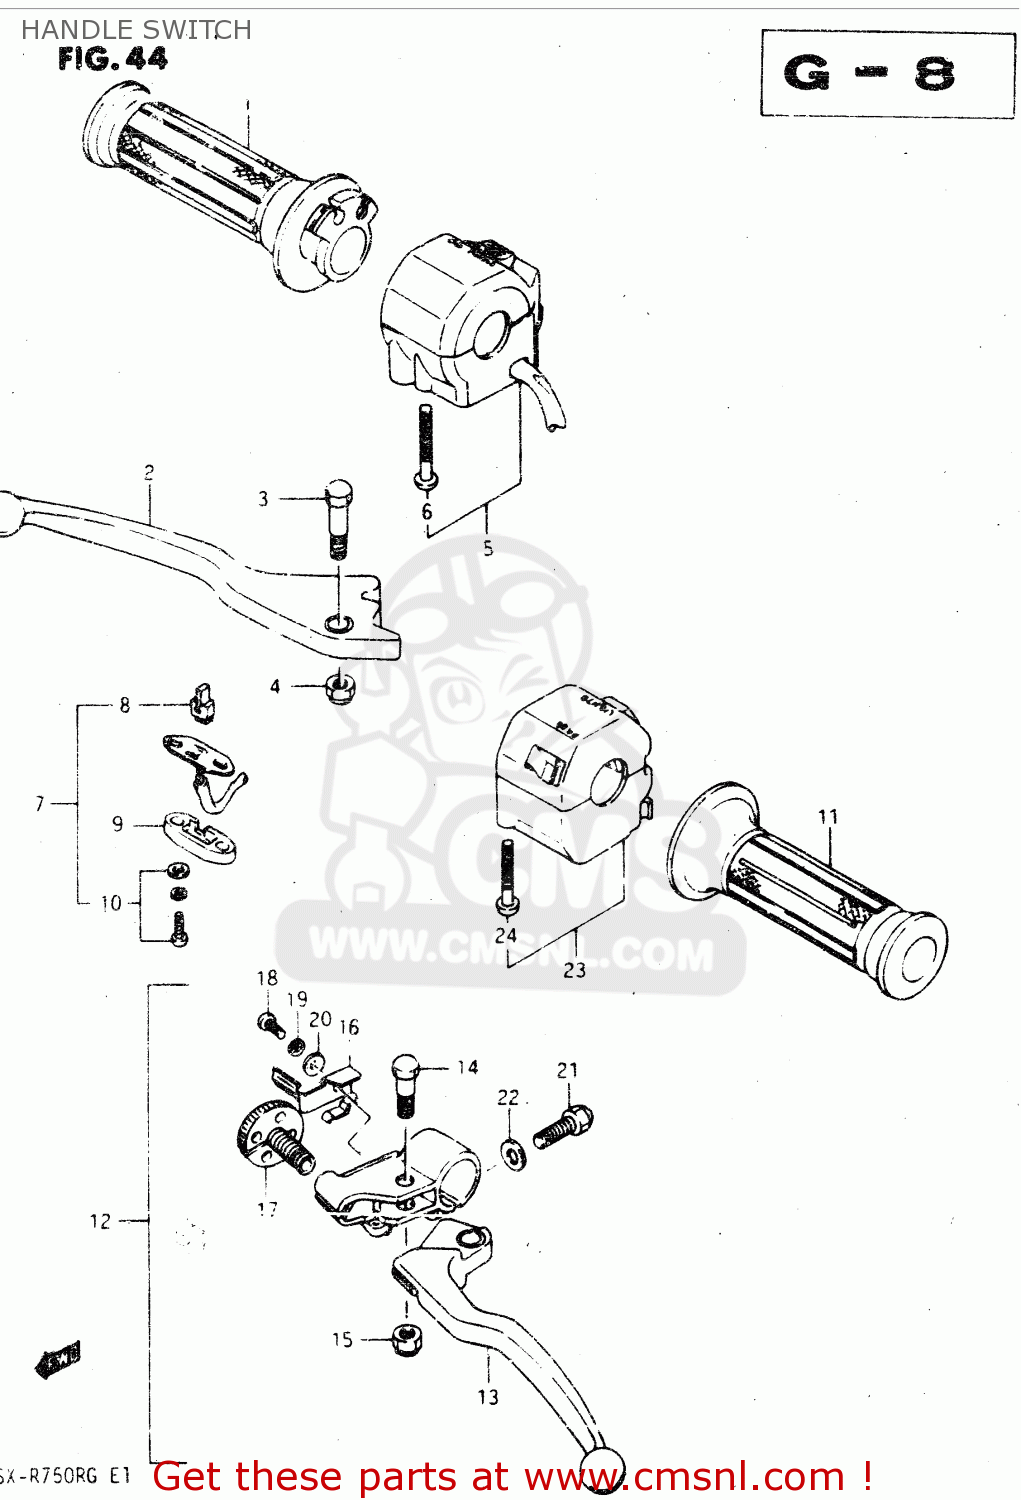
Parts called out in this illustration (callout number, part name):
1	GRIP,THROTTLE
2	LEVER,BRAKE
3	BOLT,LEVER
4	NUT
5	SWITCH ASSY,R
6	SCREW, 5X45
7	SWITCH ASSY,STOP
8	CONTACT,SWITCH
9	COVER,FR BK TERMINAL BASE
10	SCREW
11	GRIP,L
12	LEVER ASSY, CLUTCH
13	LEVER,CLUTCH
14	BOLT,LEVER PIVOT
15	NUT
16	ADJUSTER,SPRING
17	ADJUSTER,LOCK
18	SCREW
19	LOCK WASHER
20	WASHER
21	BOLT
22	WASHER
23	SWITCH ASSY, HANDLE LH
24	SCREW
